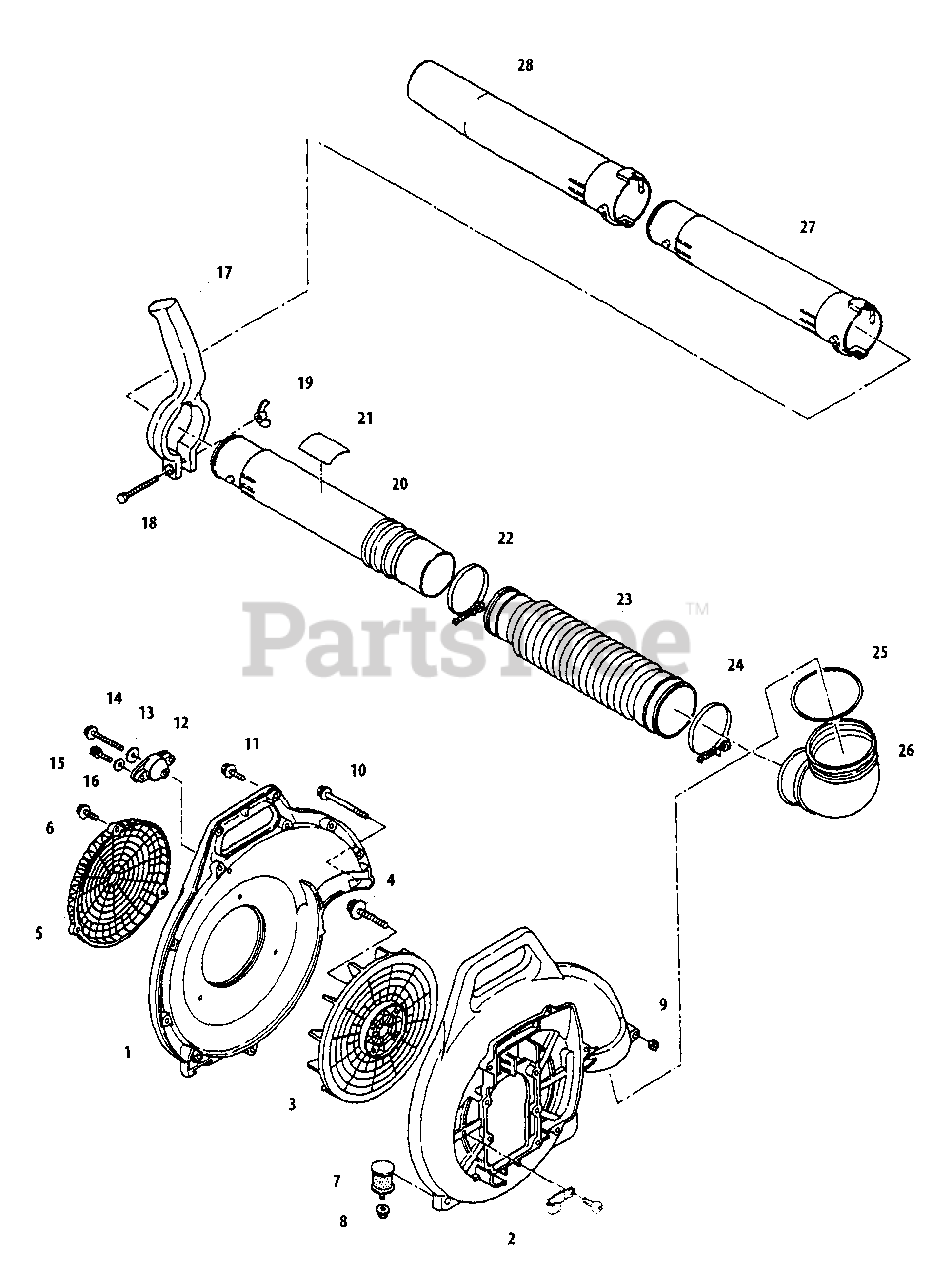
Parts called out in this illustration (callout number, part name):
1	COVER, FAN - LEFT
2	COVER, FAN - OUTER
3	FAN
4	BOLT - 6X40
5	COVER, INTAKE
6	BOLT - 5X20
7	CUSHION
8	NUT - 6 -- FLANGE
10	SCREW - 5X70
11	BOLT - 5X20
12	CUSHION
13	COLLAR - 25X5.5X2
14	BOLT - 5 -- TAPPING
15	SCREW - 5X16
16	COLLAR
17	HANDLE
18	BOLT - 6X45
19	WINGNUT
20	JOINT, PIPE
21	LABEL - TRADE
22	CLAMP
23	FLEXIBLE TUBE
24	CLAMP
25	O-RING
26	ELBOW
27	PIPE
28	NOZZLE
